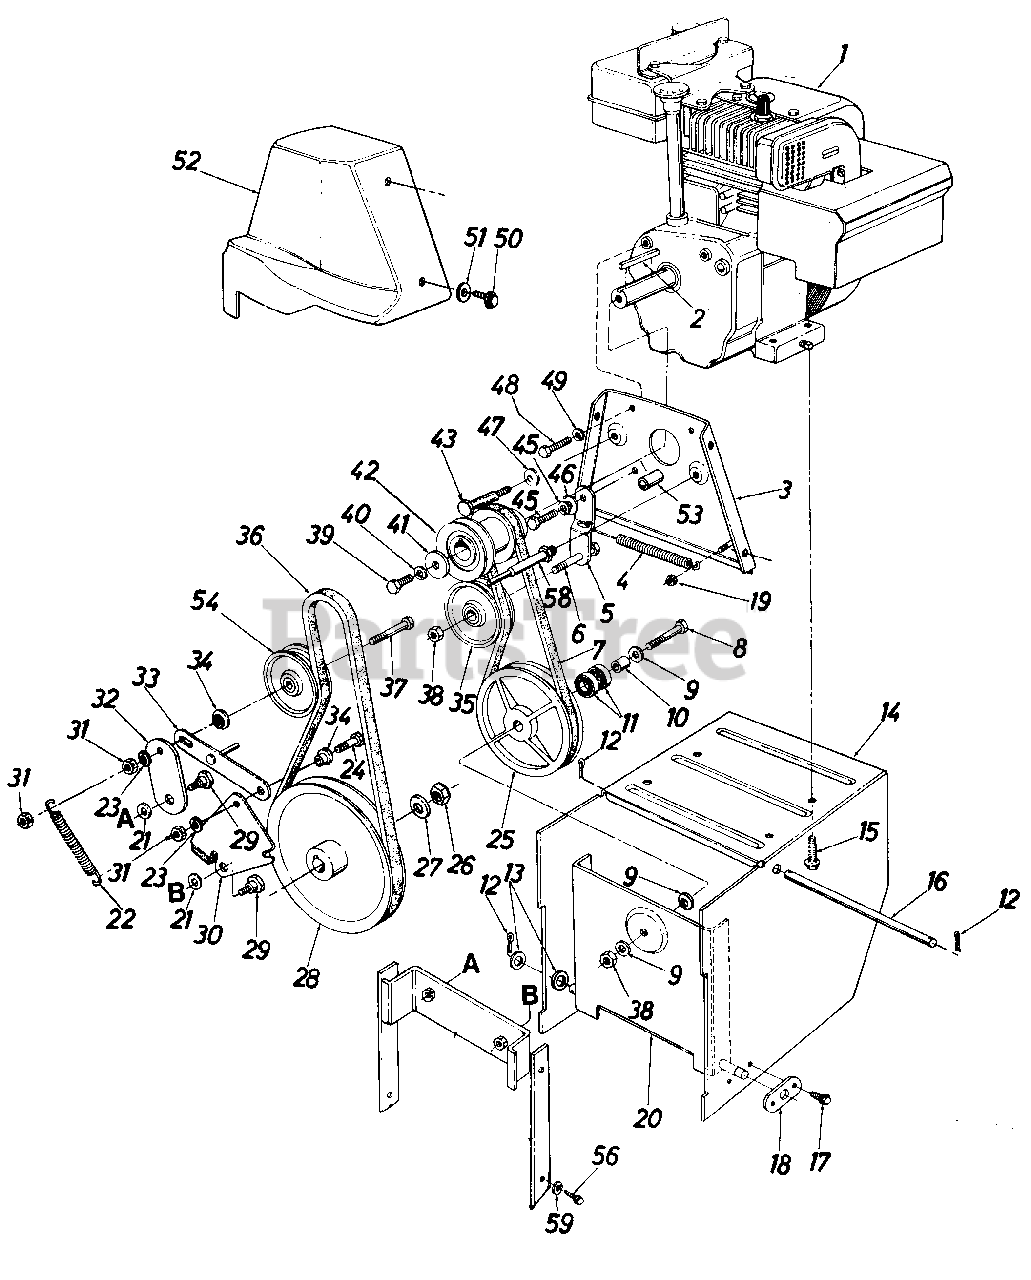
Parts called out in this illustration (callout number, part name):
1	Engine
2	Sq. Key 3/16" x 1.50" Lg.
3	Engine Plate Ass'y.
4	Extension Spring .50" O.D. x 3.97" Lg.
5	Drive Clutch Idler Brkt.
6	Hex Bolt 3/8-24 x 1.25"
7	"V"-Belt
8	Hex Bolt 3/8-24 x 1.50" Lg.
9	Bell-Wash. .40" I.D. x .88" O.D. x .06
10	Spacer .38" I.D. x .62" O.D. x .75" Lg.
11	Ball Brg. .62" I.D. x 1.38" O.D. x .44
12	Coter Pin 3/32" Dia. x .75" Lg.
13	Fl-Wash. .53" I.D. x 1.00" O.D. x .125
14	Frame Ass'y.
15	Hex Wash. Hd. Self-Tap Scr. 3/8-16 x 1.25" Lg.
16	Shaft .50" Dia. x 9.50" Lg.
17	Hex Wash. Hd. Self-Tap Scr. 1/4-20 x .50" Lg.
18	Axle Bracket
19	Hex L-Nut 1/4-20 Thd.
20	Drive Pulley Support Brkt. Ass'y.
21	Bell-Wash. .40" I.D. x 1.13" O.D.
22	Extension Spring .56" O.D. x 4" Lg.
23	L-Wash. 3/8" I.D.
24	Hex Scr. 3/8-16 x 1.25" Lg.
25	6.00" O.D. Drive Pulley Ass'y.
26	Hex Jam Cent. L-Nut 5/8-18 Thd.
27	Fl-Wash. .64" I.D. x .94" O.D. x .06
28	1/2" V-Pulley .625" I.D. x 7.50" O.D.
29	Shld. Bolt .625" Dia. x .170" Lg. (3/8-16)
30	Brake Bracket Ass'y.
31	Hex Ins. L-Nut 3/8-16 Thd.
32	Auger Clutch Idler Brkt.
33	Brake Linkage Ass'y.
34	Shld. Spacer .625" I.D.
35	Fl-ldler Pulley 2.25" O.D.
36	"V"-Belt
37	Hex Bolt 3/8-16 x 2" Lg.
38	Hex Ins. Jam L-Nut 3/8-24 Thd.
39	Hex Bolt 3/8-24 x 1.50" Lg.
40	L-Wash. 3/18" l.D.
41	Bell-Wash. .40" I.D. x 1.25" O.D.
42	Double Groove Engine Pulley
43	Shld. Scr. .498" x 3.0" Lg.
45	L-Wash. 5/16" I.D.
46	Shld. Spacer .320" I.D.
47	Bell-Wash. .40" I.D. x .88" x .06
48	Hex Bolt 5/16-24 x .62" Lg.
49	L-Wash. 5/16" I.D.
50	Hex Wash. Hd. Self-Tap Scr. 1/4-20 x .50" Lg.
51	Fl-Wash. .28" I.D. x .75" O.D. x .06
52	Belt Cover
53	Spacer
54	Fl-ldler Pulley 2.75" O.D.
56	Hex Wash. Hd. Self-Tap Scr. 3/8-16 x .75" Lg.
58	Stud 3/8-16 x 3.37" Lg.
59	L-Wash. 3/8" I.D.H.D.
